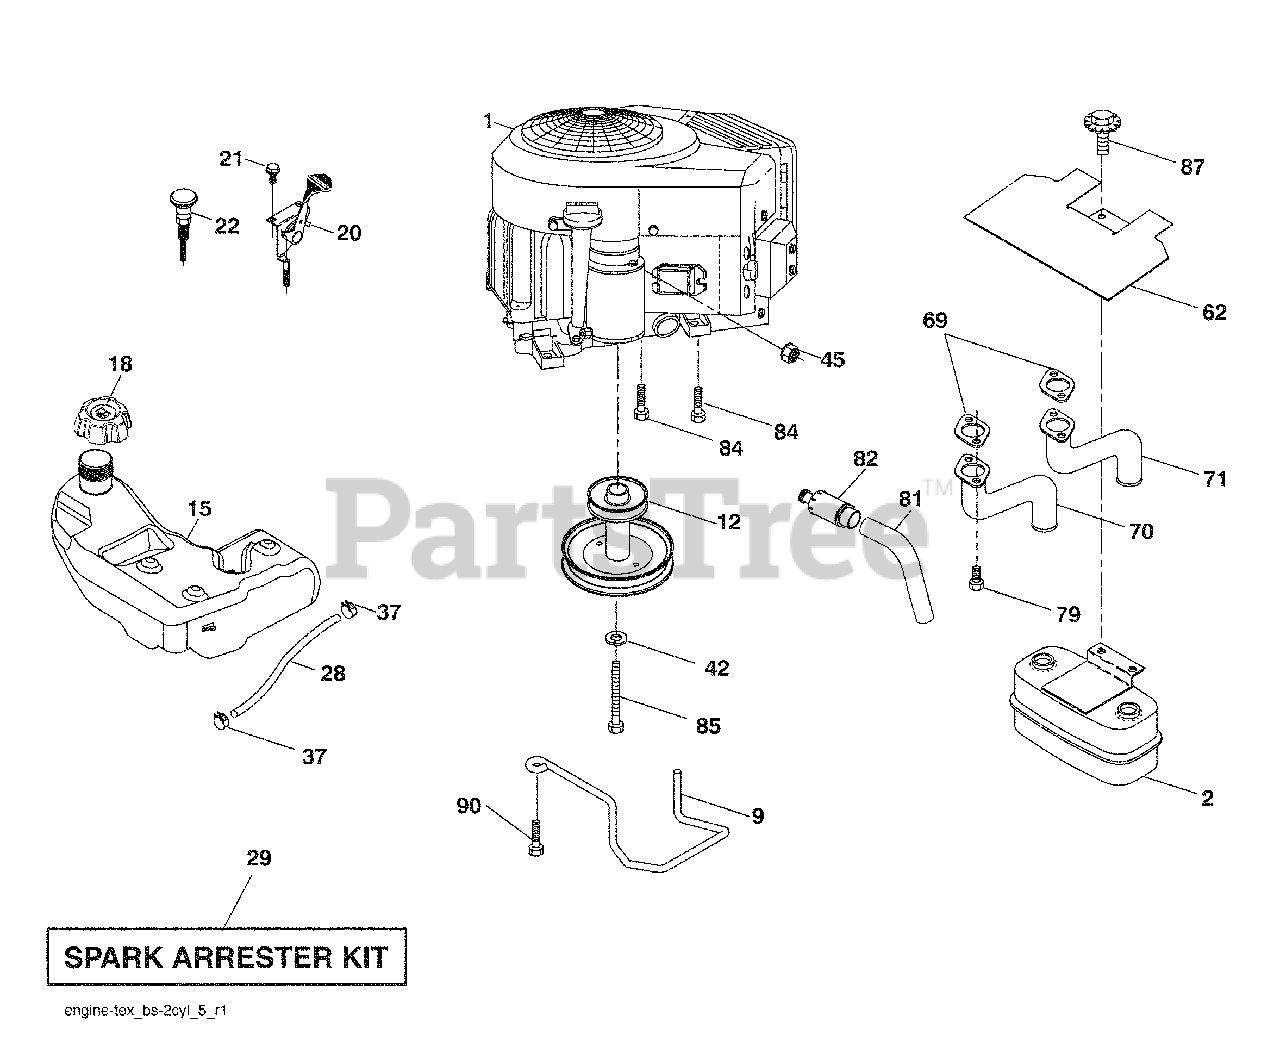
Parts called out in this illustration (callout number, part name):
9	Keeper Belt Engine
12	Pulley Engine
15	Tank Fuel
18	Cap Asm
20	Control Throttle
21	Screw #10 x 0.750 BOS Thread
22	Control Choke
28	Fuel Line
29	Spark Arrester Kit
37	Clamp Hose
42	Washer Lock 7/16
45	Nut Keps Hex 1/4-20 unc
62	Shield Heat Muffler
70	Tube Exhaust LH
71	Tube Exhaust RH
79	Screw Socket Head 5/16-18 x 1
81	Tube Drain Oil Easy
82	Plug Drain Oil
84	Screw 3/8-16 x 1-1/4
85	Bolt Hex 7/16-20 x 4 Gr. 5
87	Bolt 5/16-18 unc x 1 w/Sems
90	Screw 3/8-16 x 1
